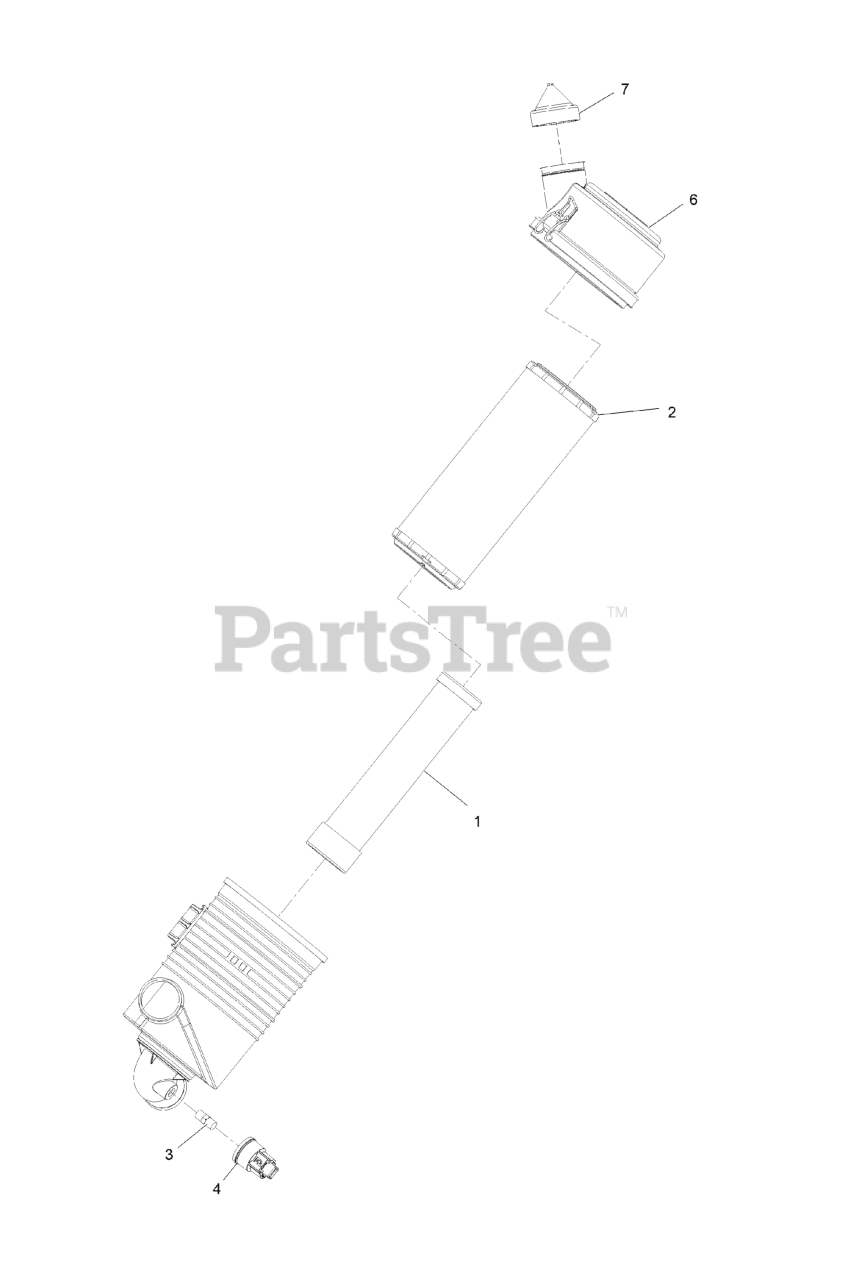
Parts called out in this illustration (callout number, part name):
1	FILTER-AIR, SAFETY
3	ADAPTER-INDICATOR
4	INDICATOR-MINI
6	COVER ASM
7	Valve-Dust-Air Cleaner
